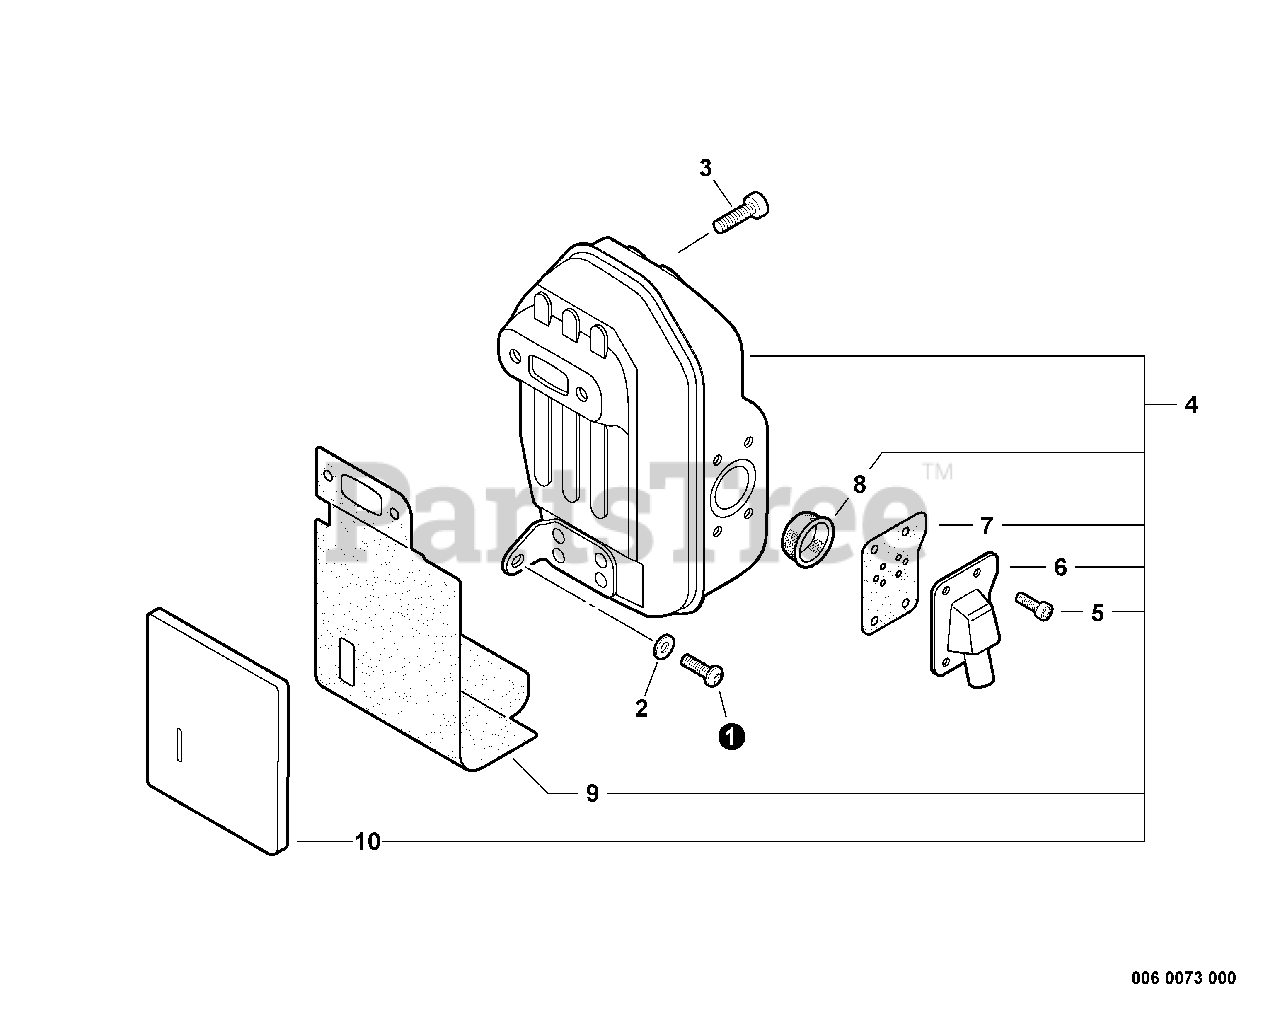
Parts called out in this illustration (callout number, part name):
1	SCREW - 5X16
2	WASHER - 5
3	SCREW - 6X20
4	MUFFLER ASSY
5	SCREW - 4X8
6	GUIDE, EXHAUST
7	GASKET, EXHAUST
8	SCREEN, SPARK ARRESTOR
9	SHIELD, EXHAUST
10	INSULATOR, EXHAUST
